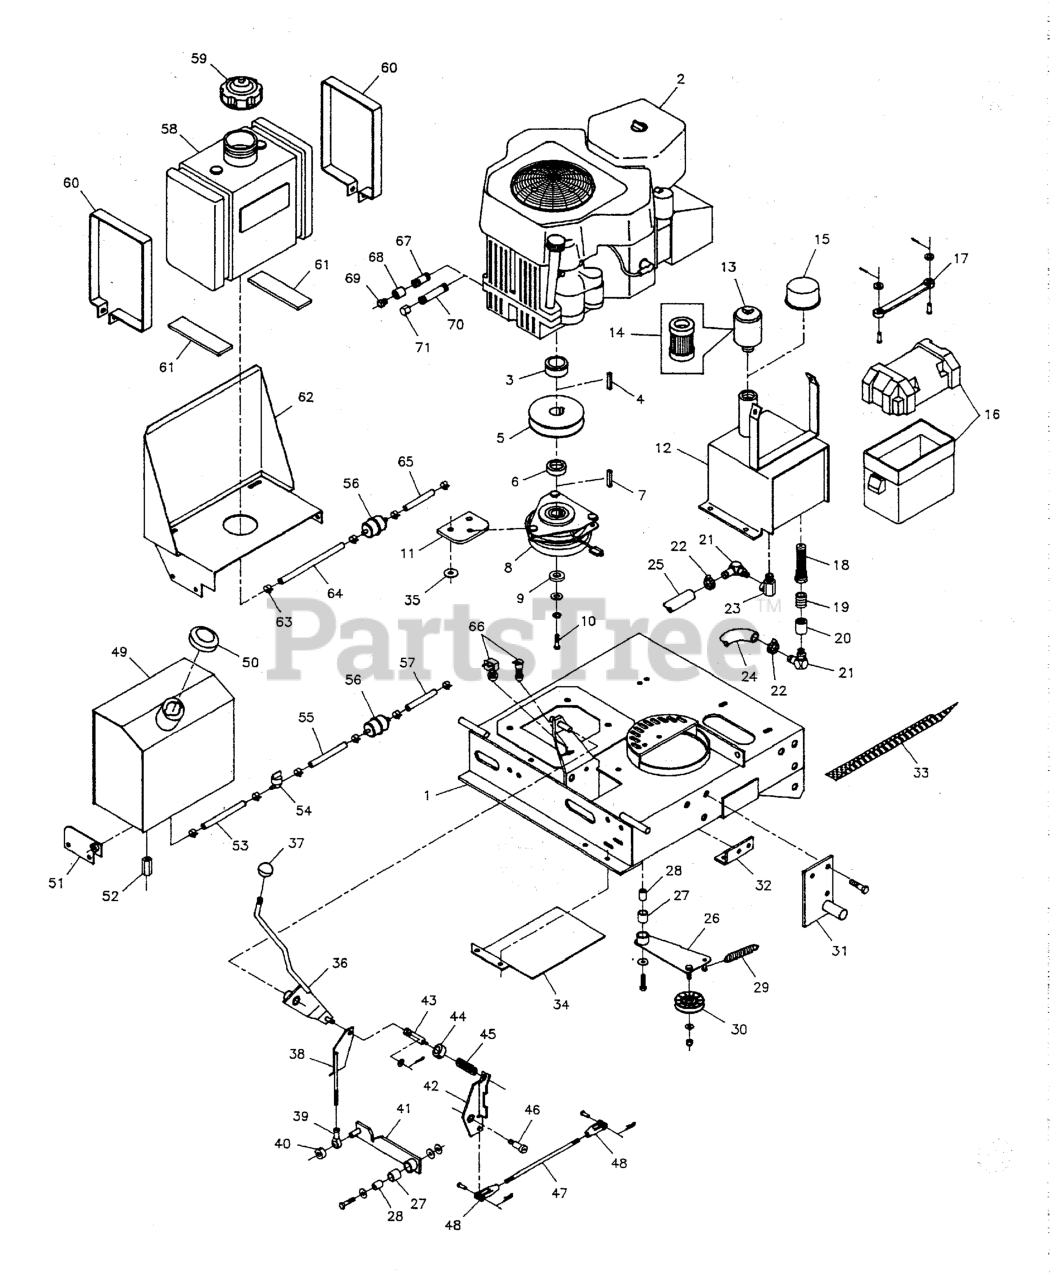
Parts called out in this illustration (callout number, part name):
1	ENGINE DECK
3	SPACER, 1.13 X 1.75 X .88
3	Spacer, Crank Shaft
4	KEY, 1/4" SQ. X 1-1/4
5	PULLEY, Crankshaft
5	Pulley, Crank Shaft
6	SPACER, 1.13 X 2.00 X .37
6	SPACER, 1.00 X 1.75 X .38
7	Key, 1/4" Sq. x 1"
8	CLUTCH, Electric, 1-1/8" Shaft
8	CLUTCH, Electric, 1" Shaft
9	SPACER, .45 x 1.62 x .37
10	CRANKSHAFT BOLT, 7/16 x 3
11	CLUTCH ANCHOR PAD
12	HYDRO TANK ASSEMBLY, Complete
12	HYDRO TANK WELDMENT
13	Air Filter Assembly
14	Air Filter Element
15	BREATHER
16	BOX, Battery
17	STRAP, RUBBER
18	Strainer, In-Line
19	NIPPLE, 1/2" NPT Close
20	COUPLER, 1/2" NPT
21	FITTING, 90 Degrees 1/2" NPT
22	CLAMP, #10 HOSE, STAINLESS
23	FITTING, 1/2 NPT Swivel, 90 Deg.
24	Transmission Inlet Hose, 4.875" Long
25	HOSE, Transmission Return, 14.75"
26	IDLER ARM ASSEMBLY, Complete
27	BUSHING, BRASS, 3/4 X 1 X 1
28	SPACER, .32 X .75 X 1.06, PM
29	SPRING, Extension
30	PULLEY, IDLER ASSEMBLY
31	Pivot Bracket - RH
31	Pivot Bracket - LH
32	Plate Bracket
33	Grass Screen
34	Plate, Skid
35	WASHER, .34 X 1.25 X 10 GA
36	BRAKE LEVER WELDMENT
36	Brake Lever Weldment
37	KNOB, PLASTIC, 1/2-13
37	Black Knob
38	BRAKE LOCK LINK
39	BALL JOINT 5/16-24 RH FEMALE BRONZE RACE
40	COLLAR, 5/16" Set
41	NEUTRAL LOCK LEVER, Complete
42	BRAKE ROCKER ARM
43	SPRING BAR ASSEMBLY
44	COLLAR, 5/8" Set
45	SPRING, Compression
46	Bolt, 3/8-16 - 112" Dia. x I" Shoulder
47	Rod, Brnke Linkage
48	CLEVIS, 5/16-24, Plastic
49	Fuel Tank Assembly
50	AXLE, Caster Wheel
51	Fuel Tank Mount Plate
52	Coupling Nut
53	Fuel Line, 19" Long (filter to engine)
54	VALVE, Fuel Shut-Off
55	HOSE, 1/4" FUEL, 9.00"
55	Fuel Line, 19" Long (filter to engine)
56	FUEL FILTER (SV)
57	FUEL FILTER (SV)
57	HOSE, 1/4" FUEL, 6" LONG
58	TANK, FUEL, PLASTIC, 6 GALLON W/ FUEL LINE
58	BUSHING-FUEL TANK RED RUBBER
59	Gas Cap
60	Strap, 6 Gal. Fuel Tank
61	Pad, Rubber Mount
62	Mount, Fuel Tank
63	CLAMP, Hose
64	1/4" Fuel Line, 29" Long
64	Fuel Line, 25" Long (tank to filter)
65	Fuel Line, 25" Long (tank to filter)
65	Fuel Line, 19" Long (filter to engine)
66	Switch, Plunger N. O.
66	Parking Brake Switch
67	Pipe Nipple
68	Coupler
69	Pipe Plug
70	Nipple, 3/8" Nl'T x 4-1/2"
71	CAP, 3/8" NPT
